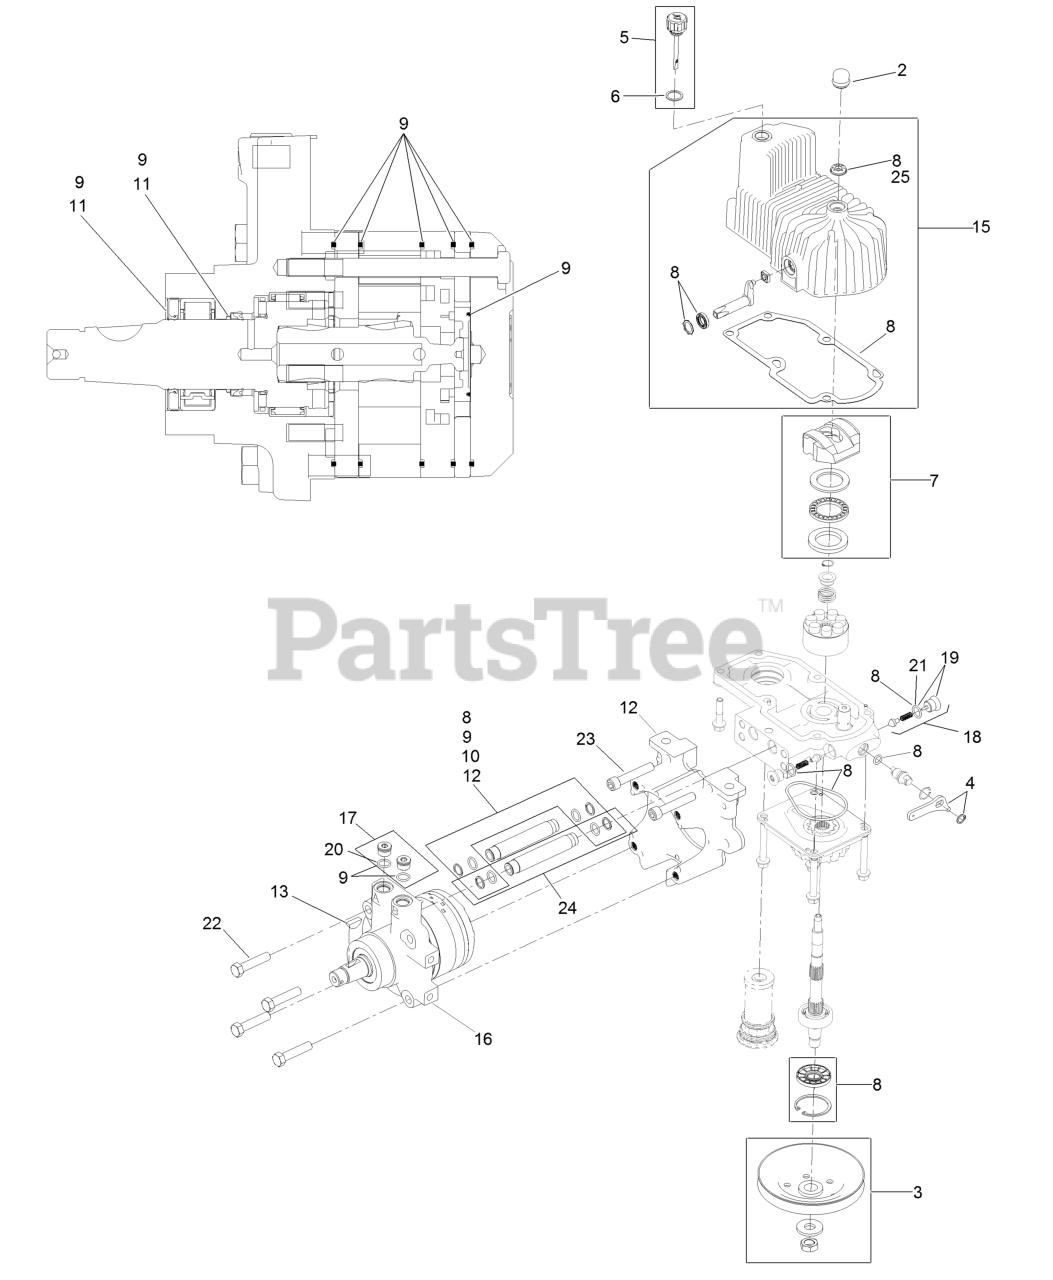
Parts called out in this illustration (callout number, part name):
2	Cover-Shaft, Hydro
3	Pulley Kit
4	Handle-Bypass Valve,Hydro
5	Dipstick-Hydro W/Gasket
6	Gasket-Dipstick, Hydro
7	Swash Block Kit
8	Pump Seal Kit
9	Motor Seal Kit
10	Tube Seal Kit
11	Output Shaft Seal Kit
12	Nose Cup-Uht
13	Key-Woodruff
15	Housing-LH
16	Motor-Hydraulic LH 240Cc
17	Magnetic Plugs Service Kit
18	Check Valve ASM
19	Plug-Check (W/O-Ring)
21	O-Ring-Check Valve
22	Screw HH
23	Screw-HSH
24	Hydraulic Tube Kit
25	Seal-Fan Drive
99	Puller-Pulley
99	Flow Test Kit
